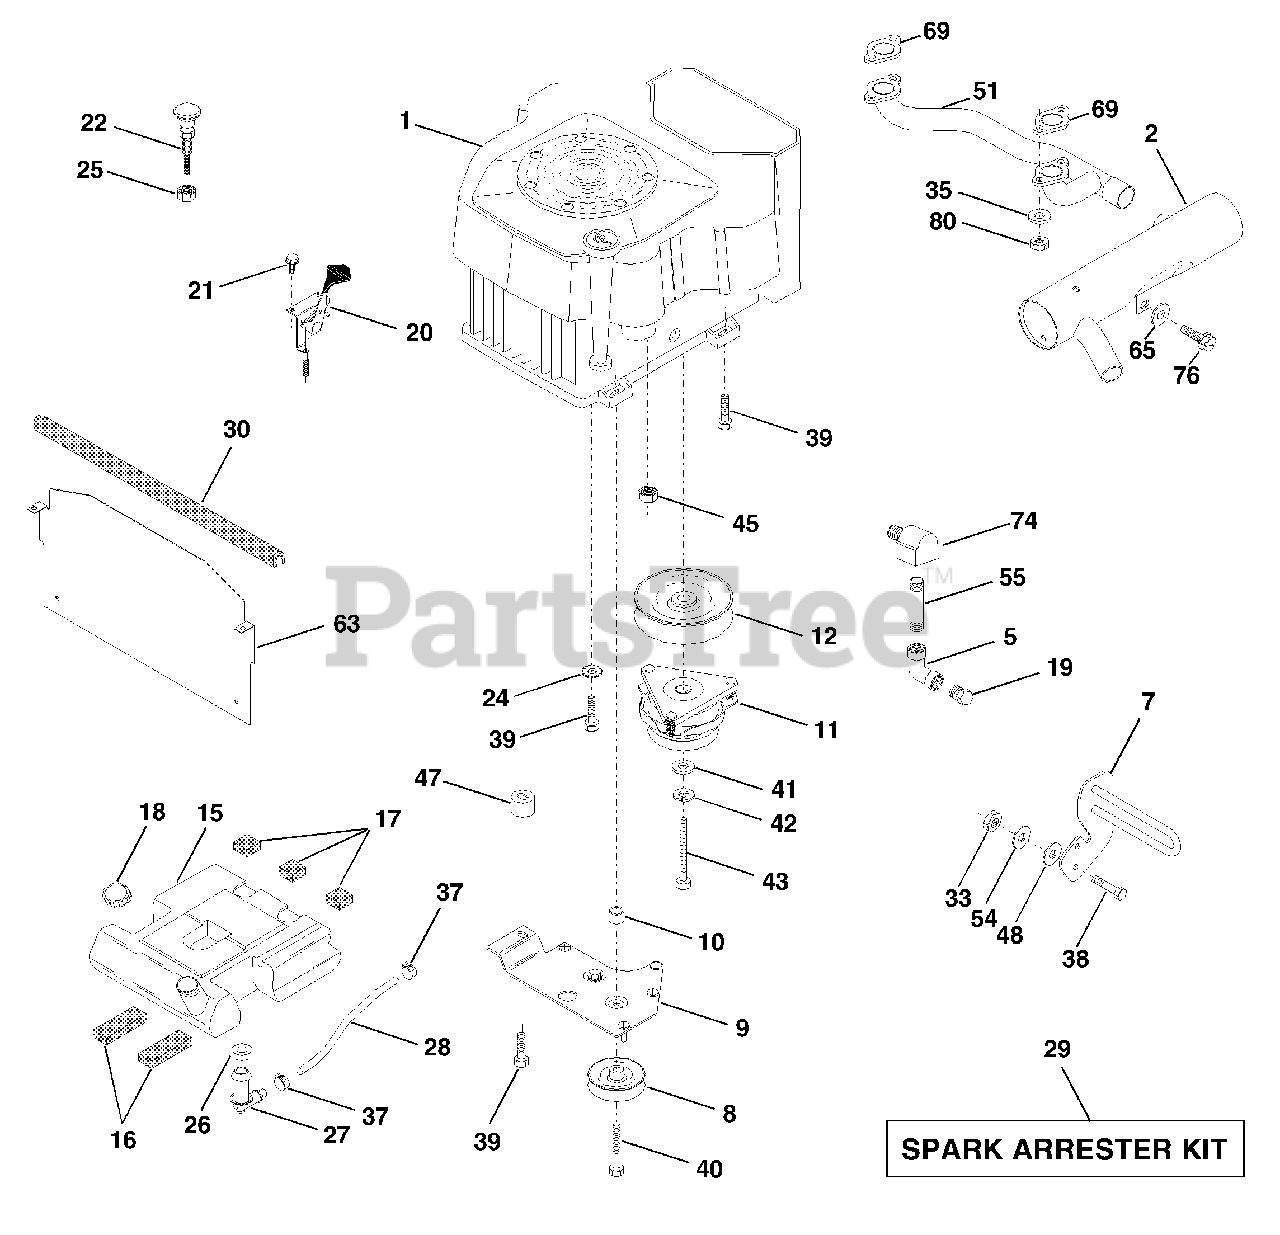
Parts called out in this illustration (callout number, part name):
2	Muffler Side
5	Elbow STD 90 Degree 3/8-18 NPT
7	Muffler Assembly Guard
8	Pulley V-Idler
9	Keeper Asm Belt Engine VGT 96
11	Clutch Electric
12	Pulley Engine VGT Elect Clutch
15	Tank Fuel Rear
16	Pad Spacer
17	Pad Spacer
18	Cap Asm Fuel W/Sym Vented
19	Plug Oil Drain
20	Control Throttle
21	Screw Hex Thd Cut 1/4-20 X 5/8
22	Control Choke
24	Washer Ext Tooth 3/8
25	Nut Keps 3/8 - 24 UNF
26	Bushing
27	Stem Tank Fuel
28	Fuel Line
29	Spark Arrester Kit
30	Extrusion Hood
33	Nut, Hex W/Ins. 3/8-16 UNC
35	Washer Split
37	Clamp Hose
38	Bolt, Fin Hex 3/8-16 UNC x 1-1/2
39	Screw TT 3/8-16 x 2-1/4 UNC
40	Screw TT 3/8-16 x 4 UNC
41	Washer 1-1/2 OD X 15/32 ID X .250
42	Washer Lock 7/16
43	Bolt Hex 7/16-20 X 4-1/4 Ga 5
45	Nut Flange 1/4-20 Starter Nut
47	Spacer Engine
48	Washer 13/32 x 1-1/4 x 7 Ga.
51	Manifold Pipe VGT
54	Washer Flat 13/32 x 7/8 x 14 Ga.
55	Nipple, Pipe 4-1/2"
63	Shield, Heat VGT YP/Husq.
65	Washer 13/32 x 1 x 14 Ga.
69	Gasket
74	Elbow Street Brass
76	Screw Thrdrol 3/8-16 x 3/4 Ty-TT
80	Nut Flange
